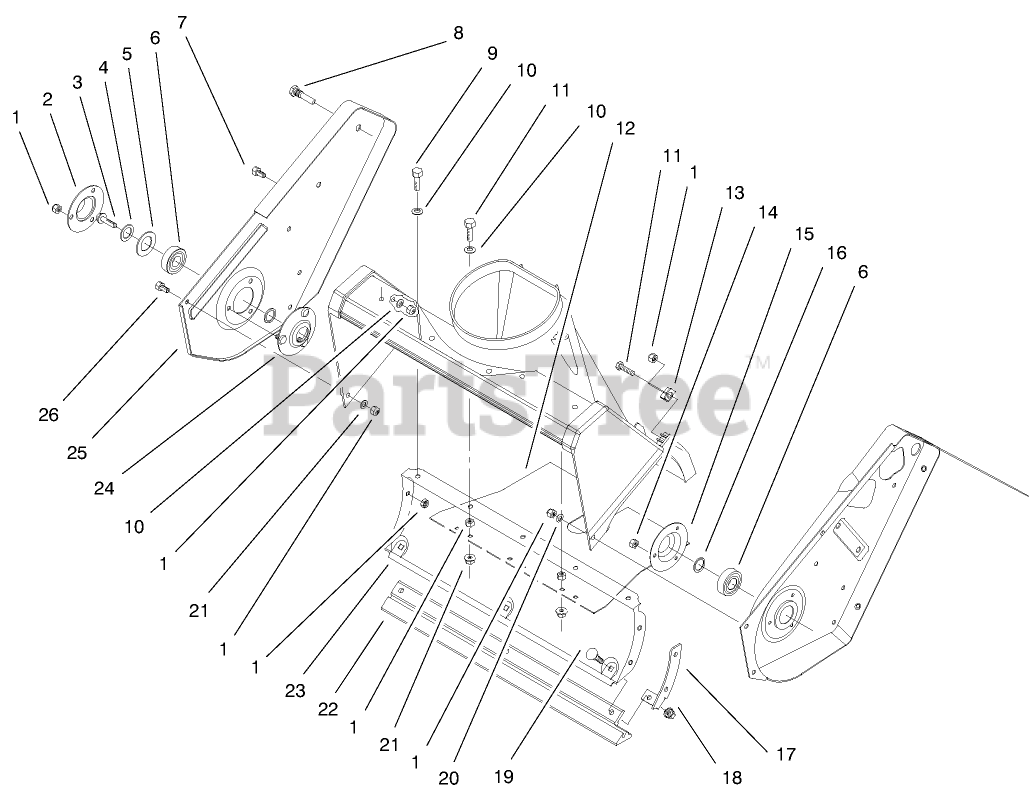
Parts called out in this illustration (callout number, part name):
1	NUT-LOCK, NI
2	RETAINER-BEARING
3	SCREW-HHF
4	WASHER-FLAT
5	WASHER-RUBBER
6	BEARING-BALL
7	SCREW-HH
8	PIN-ROTOR
9	SCREW-HH
10	WASHER-FLAT
11	SCREW-HH
12	COVER-BOTTOM
13	BRACKET-HOUSING
14	NUT-LOCK, NI
15	FLANGE-BEARING
16	WASHER-THRUST
17	BRACKET-HOUSING, LOWER
18	NUT-KEPS
19	SCREW-CARR
20	WASHER-FLAT
21	NUT-LOCK, HHF
22	SCRAPER
23	HOUSING-LOWER
24	FLANGE-BEARING
25	PLATE-SIDE, RH
26	SCREW-HWH
